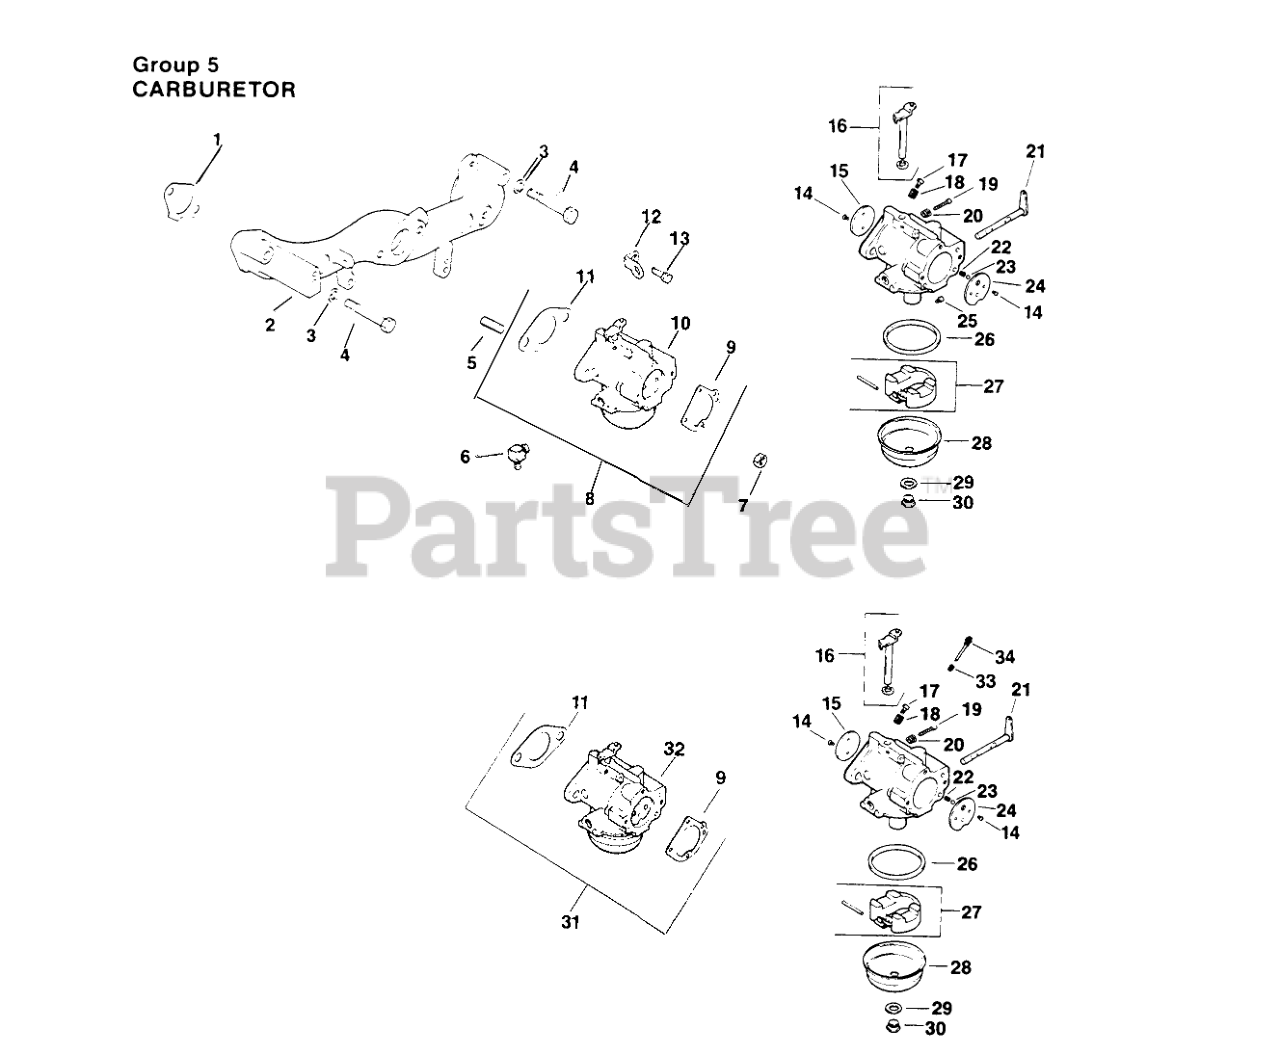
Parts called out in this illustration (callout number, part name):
1	Gasket-Intake Manifold
2	Manifold, Intake
3	Washer
4	Screw
5	Clip
6	Connector-Hose
7	Nut
8	Carburetor Kit w/Gaskets
9	Gasket-Elbow
10	Carburetor Assembly For Information Only
11	Gasket
12	Strap Lifting
13	Screw
14	Screw
15	Plate-Throttle
16	Shaft-Throttle w/Lever & Seal
17	Needle-Idle Fuel Adj.
18	Spring
19	Needle-Main Fuel
20	Spring
21	Lever-Choke
22	Spring-Choke Friction
23	Ball-Choke Friction
24	Plate-Choke
25	Jet-Main
26	Gasket-Bowl
27	Kit-Float
28	Bowl-Fuel
29	Gasket-Retainer Screw
30	Screw-Bowl Retainer
31	Carburetor Kit w/Linkage
32	Carburetor Assembly For Information Only
33	Spring
34	Needle-Main Fuel
